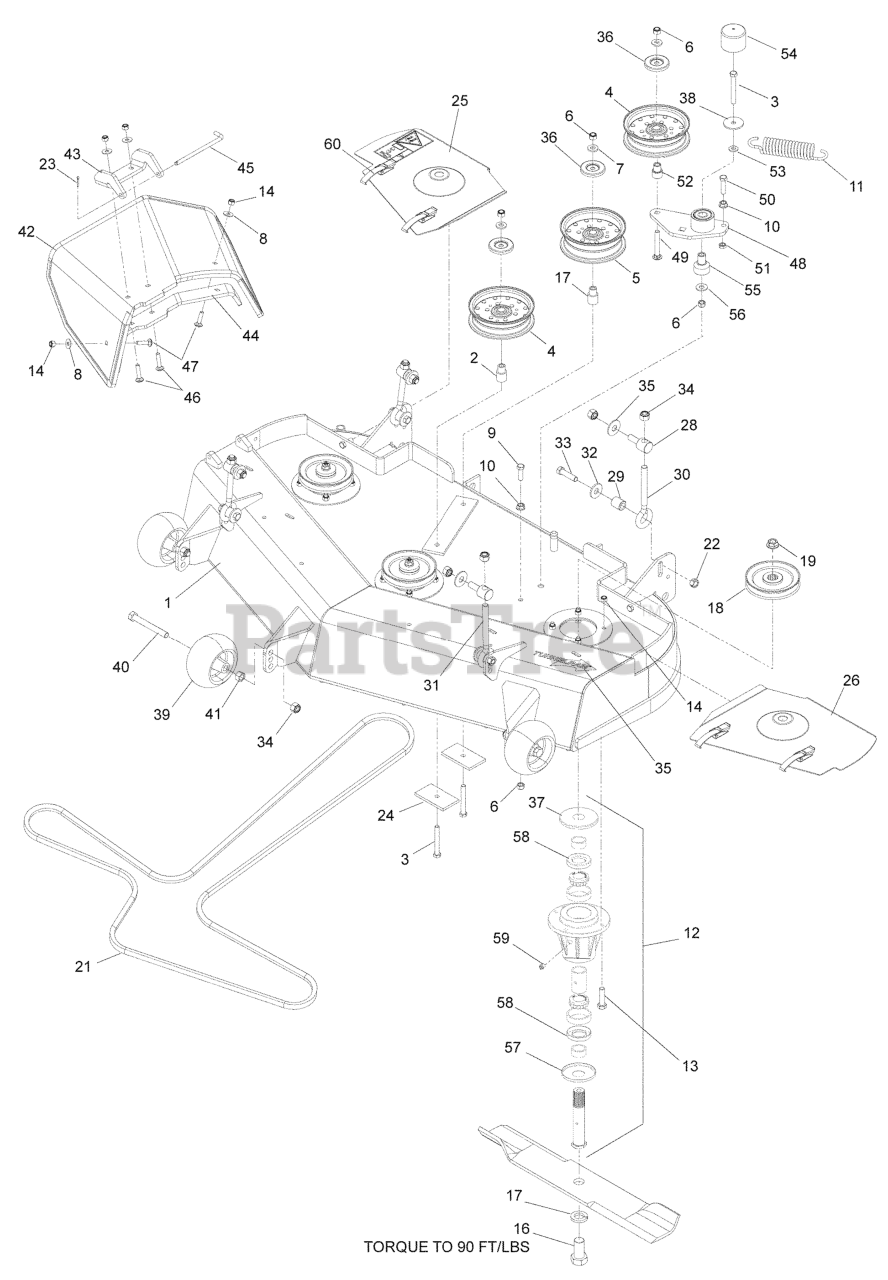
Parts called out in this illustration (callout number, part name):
1	DECK W/DECALS 48" HUS
2	IDLER BUSHING
3	HCS 3/8C X 3
4	IDLER PULLEY
5	IDLER PULLEY (TALL)
6	NUT 3/8-16 NYLOC
7	WASHER, 3/8 THICK
8	WASHER 5/16 FLAT
9	HCS 3/8C X 1 1/4 GR5
10	NUT 3/8C WHIZ
12	HOUSING ASM, 52/61
13	HCS 5/16C X 1 1/4
14	NUT 5/16 NYLOC
15	BLADE OEM 16 1/4"
16	HCS 5/8F X 1 1/4
17	LOCKWASHER 5/8
18	PULLEY 42-48
19	NUT FLANGE 3/4-16
20	HCS 7/16-20 GD 8 SPEC
21	BELT, DECK 48"
22	NUT 7/16C CENTERLOCK
23	RP_COTTER PIN 1/8 X 3/4
24	SUPPORT PLATE
25	48 BELT SHIELD ASM - RH
26	48 BELT SHIELD ASM - LH
27	DECAL, TUNNEL RAM 6"
28	SWIVEL, DECK HEIGHT ADJ
31	EYEBOLT, 1/2-13 X 5.88
32	WASH USS FLAT 1/2
33	HCS 7/16 - 14 X 1 3/4
34	NUT 1/2-13 HEX NYLOC ZD
35	WASHER-.533IDX1.37OD
36	DUST SHIELD
37	TOP DUST CAP
38	WASHER, 3/8 SPEC
39	GAUGE WHEEL
40	HCS 1/2-13 X 4 GR 5 ZD
41	NUT HEX 1/2
42	CHUTE, RUBBER DISCHARGE 42/48"
43	PIVOT BRACKET - RUBBER CHUTE
44	BRACKET, REINF-CHUTE
45	PIN, CHUTE PIVOT
46	RHSNB 5/16-18 X 1-1/2 GR 5 ZD
47	BOLT, CARRIAGE 5/16X1-1/4
48	ARM-IDLER W/BRG
49	RHSNB 3/8-16 X 2.75
50	HCS 3/8-16 X 1-1/2
51	NUT 3/8-16 HEX JAM
52	BUSHING, IDLER
53	WASHER 3/8 SAE FLAT
54	CAP, VINYL
55	PIVOT, BEARING
56	WASHER 3/8 FLAT
57	BOTTOM DUST CAP
58	SHAFT SEAL
59	PLUG-VENTED
60	DRAW LATCH
